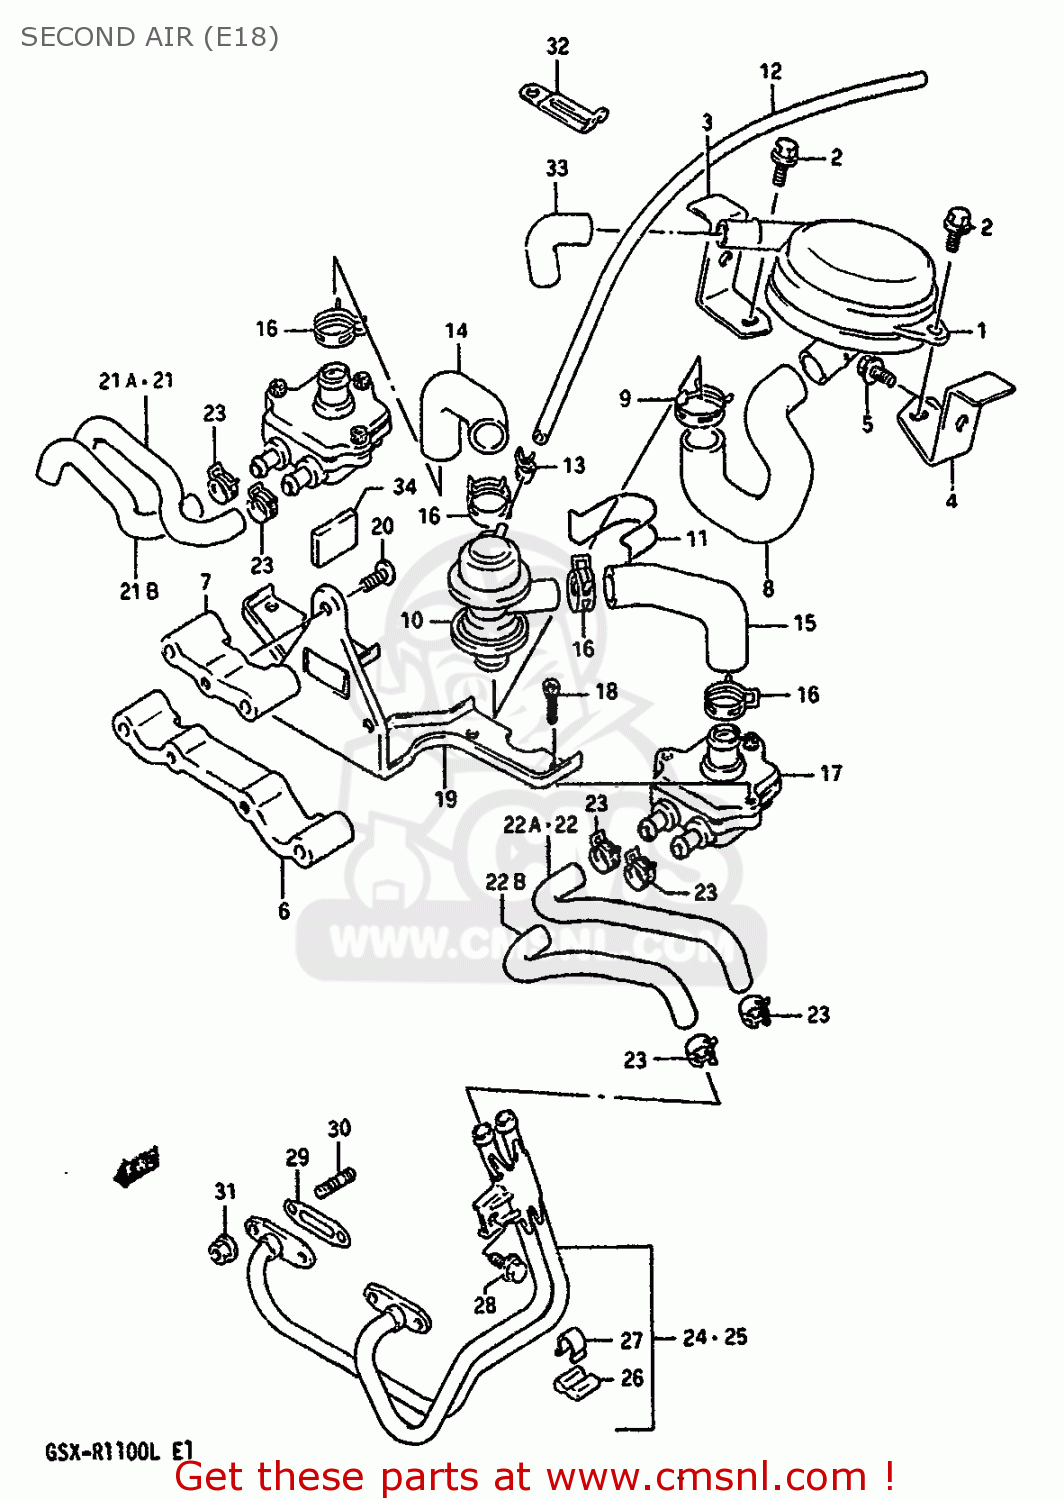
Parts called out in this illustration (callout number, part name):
1	CLEANER ASSEMBLY,SECOND AIR
2	BOLT
3	BRACKET,SECOND AIR CLEANER
4	BRACKET,SECOND AIR CLEANER
5	BOLT
6	SPACER,SECOND AIR BRACKET,LOWER
7	SPACER,SECOND AIR BRACKET,UPPER
8	HOSE,SECOND AIR NO.3
9	CLIP
10	VALVE ASSEMBLY,AIR SWITCH
11	CLAMP,SWITCHING VALVE
12	HOSE
13	CLAMP
14	HOSE,SECOND AIR NO.2,RIGHT
15	HOSE,SECOND AIR NO.2,LEFT
16	CLIP
17	VALVE ASSY,2ND AIR REED
18	BOLT
19	BRACKET,SECOND AIR VALVE
20	SCREW
21	HOSE,SECOND AIR NO.1,RIGHT
21A	HOSE,SECOND AIR NO.1,RIGHT,INLET
21B	HOSE,SECOND AIR NO.1,RIGHT,OUTLET
22	HOSE,SECOND AIR NO.1,LEFT
22A	HOSE,SECOND AIR NO.1,LEFT,INLET
22B	HOSE,SECOND AIR NO.1,LEFT,OUTLET
23	CLIP
24	PIPE ASSEMBLY,SECOND AIR,RIGHT
25	PIPE ASSEMBLY,SECOND AIR,LEFT
26	(CA) CUSHION
27	(CA) CLIP,SECOND AIR PIPE
28	BOLT 6X12
29	GASKET,SECOND AIR PIPE (NAS)
30	STUD BOLT
31	NUT 6MM
32	CLAMP L:35
33	(CA) HOSE,SECOND AIR CLEANER
34	CUSHION
